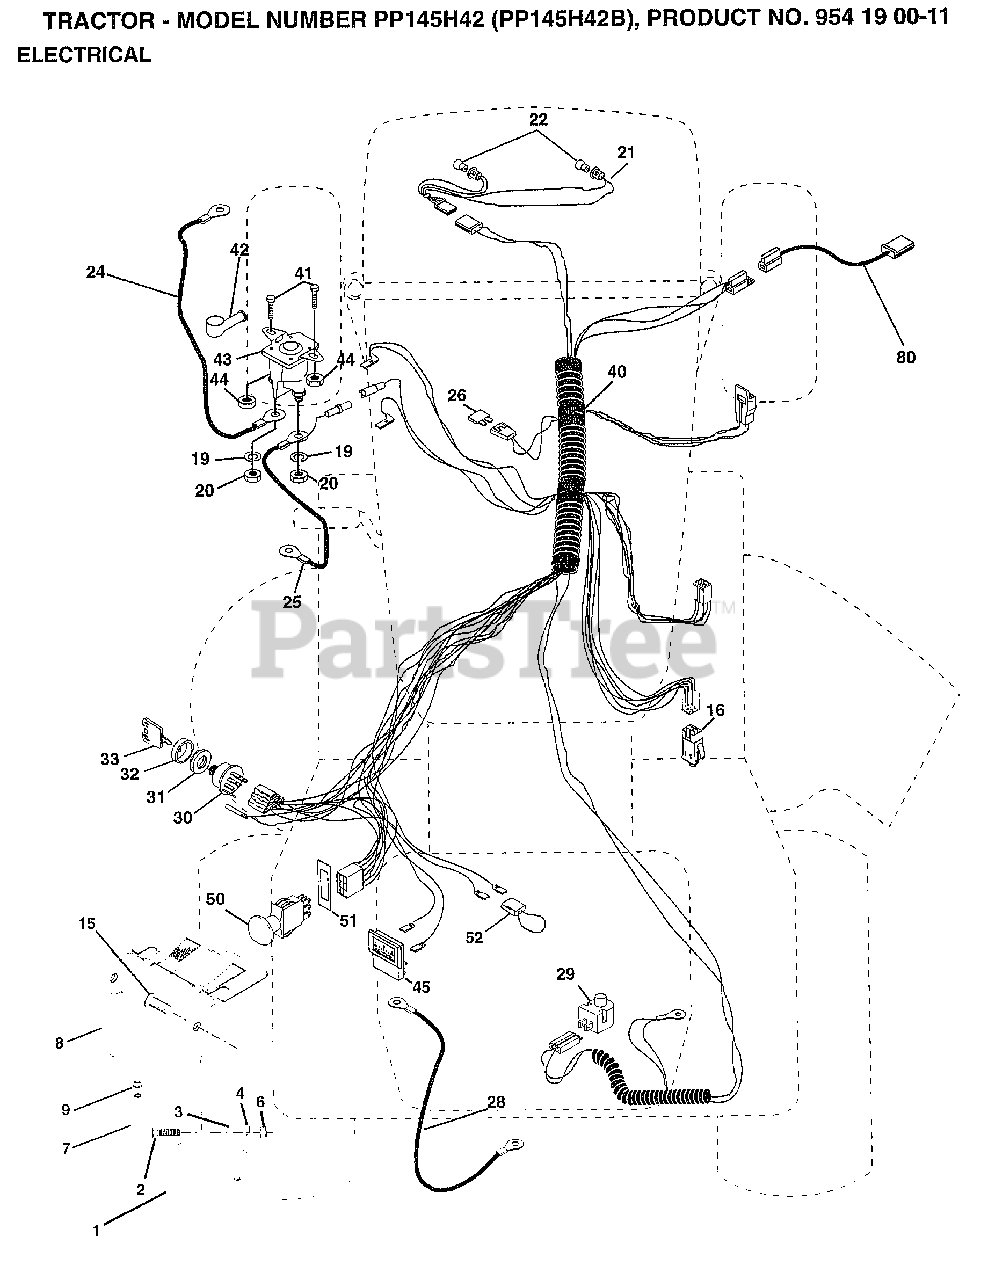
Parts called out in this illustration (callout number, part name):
2	BOLT LT
3	WASHER
4	LOCKWASHER
7	TUBE T
8	"CASE,BATTERY.MECH"
9	HOSE CLAMP T
15	FASTNER.SNAP-IN
16	SWITCH INTERLOCK
20	NUT
21	"HARNESS,LIGHT SOC"
22	HEADLAMP BULB
24	CABLE ASM.
25	CABLE.BTRY.6GA.RD
26	FUSE HYT
28	CABLE T
29	SWITCH SEAT
30	SWITCH IGN 4POS
31	NUT IGNITION
32	COVER KEY SWITCH
33	KEY
40	HARNESS IGNITION
41	BOLT HXHD FIN
44	NUT HXKEP 1/4X20
50	PTO SWITCH.BLK
51	RING RETAIN PTO
52	PROTECTION LOOP
80	HARNESS.CLUT.EVX.
